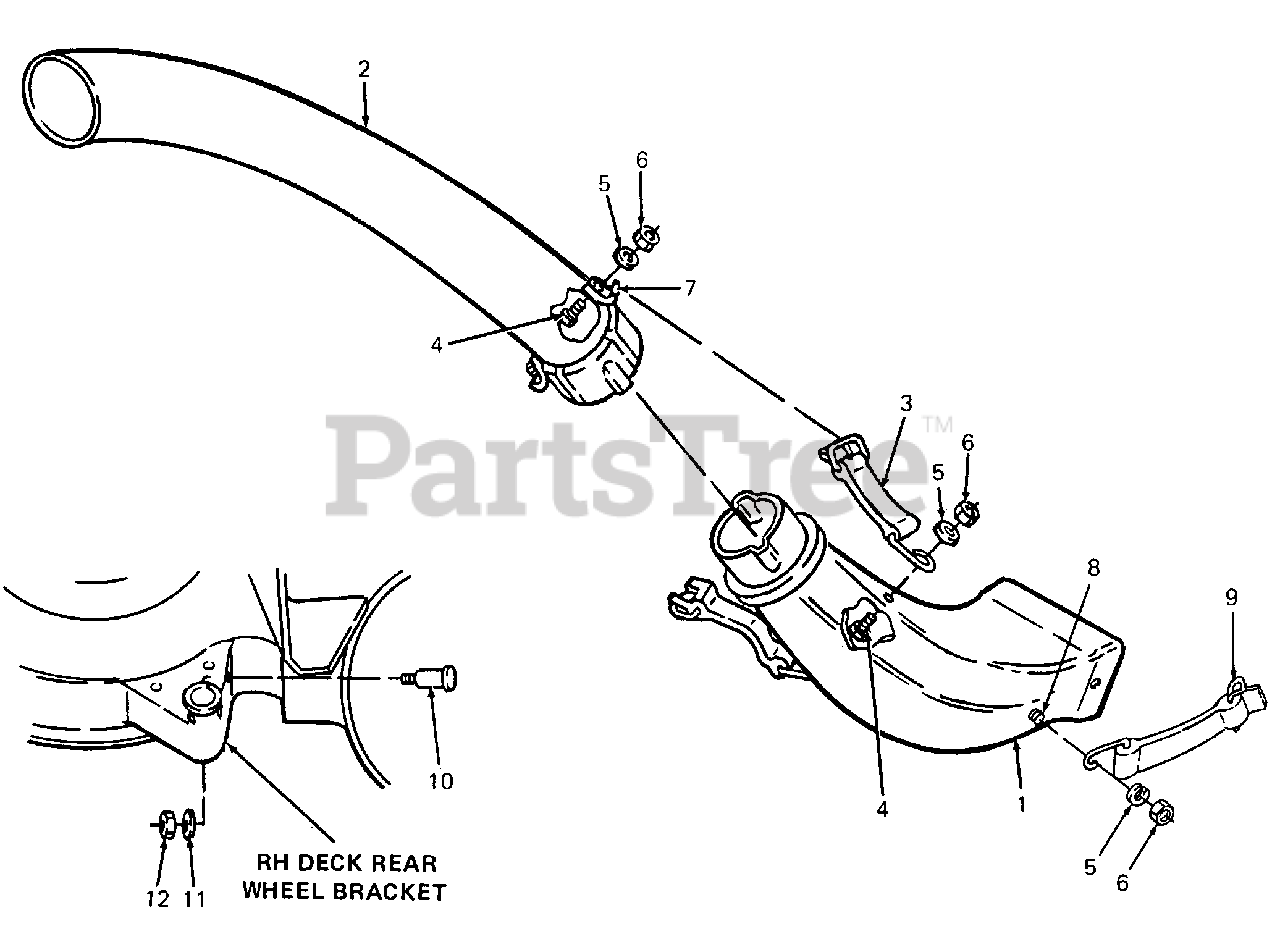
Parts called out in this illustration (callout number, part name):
1	Chute, Discharge
2	Tube, Catcher Elbow
3	Strap Assy, Retainer
4	Screw, Hex, 1/4-20 X .50 Lg
5	Washer, Spring, .265 X .562
6	Nut, Hex Insert Lock, 1/4-20
7	Hook Bracket, Retainer
8	Screw, Hex Cap, 1/4-20 X .62 Lg
9	Strap Assy, Chute Retainer
10	Screw, Shoulder
11	Washer, Bell
12	Nut, Hex Center Lock, 3/8-16
